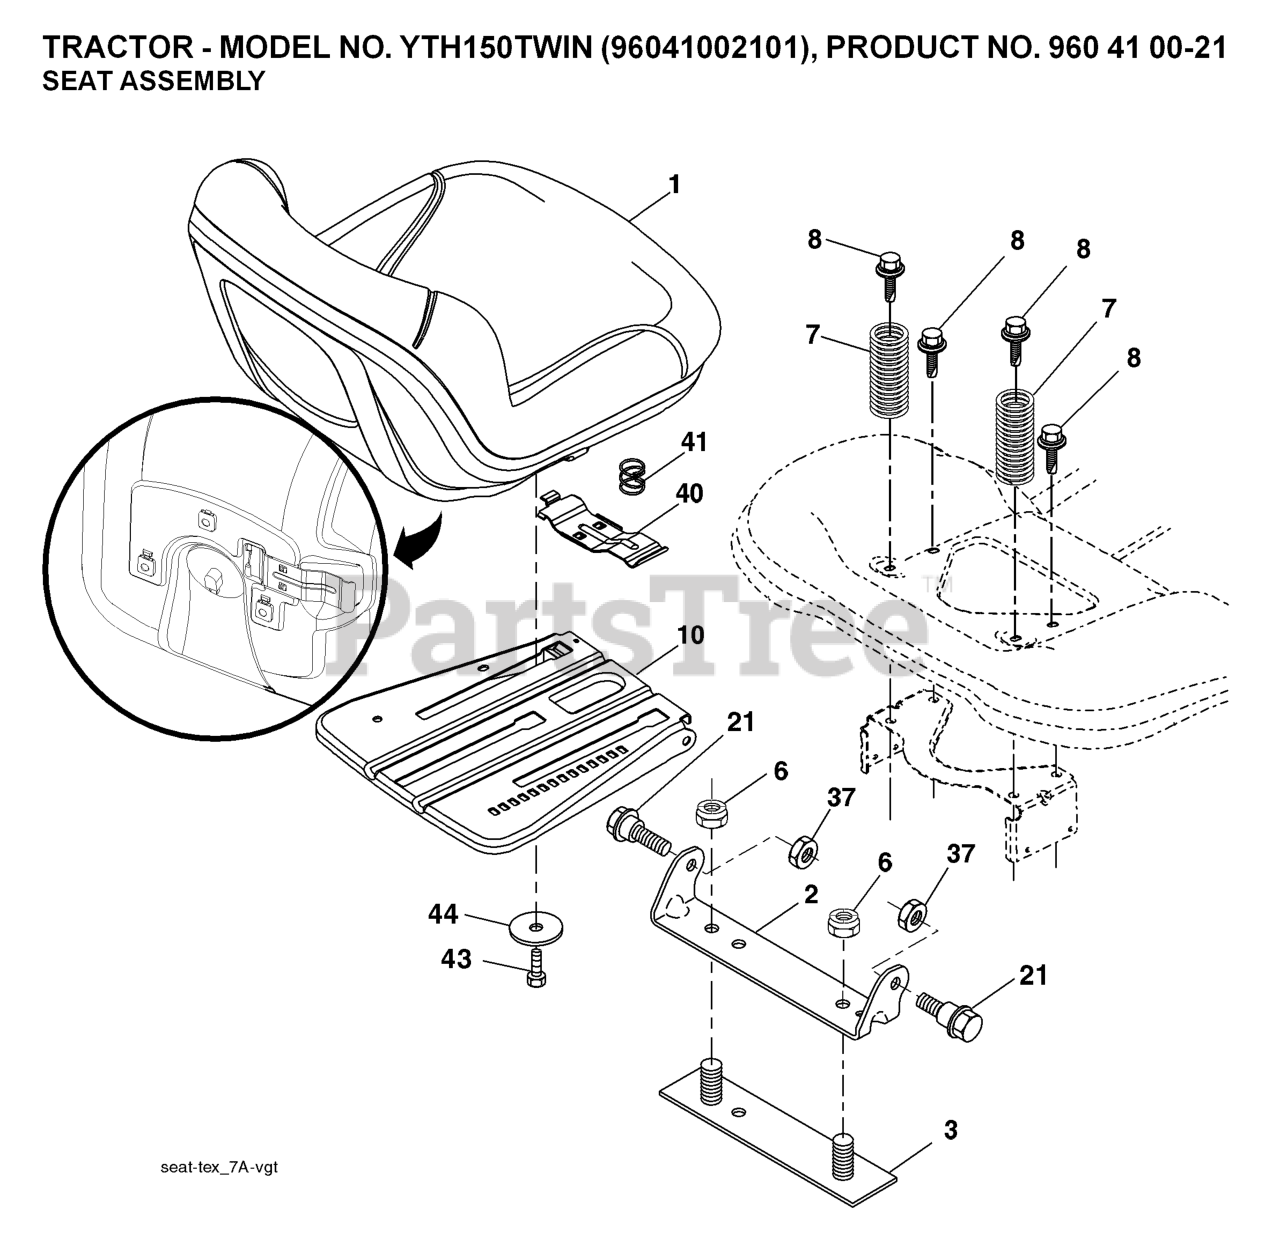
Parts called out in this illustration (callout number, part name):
1	SEAT - GREY
2	BRKT.PIVOT.FENDER
3	STRAP
6	NUT
7	SPRING COMPRESSION
8	BOLT.5/16-18UNCX3/4 W/SEMS.BLK
10	PAN.ASM.SEAT.3PT
21	BOLT.SHOULDER.5/16-18
37	NUT.71038.31-18.HEX.NYLOCK
40	HANDLE.SLIDE.SEAT.TEX.BLACK
41	SPRING.LATCH.SEAT.TEX
44	WASHER 13/32 X 2-3/8 X 12GA
